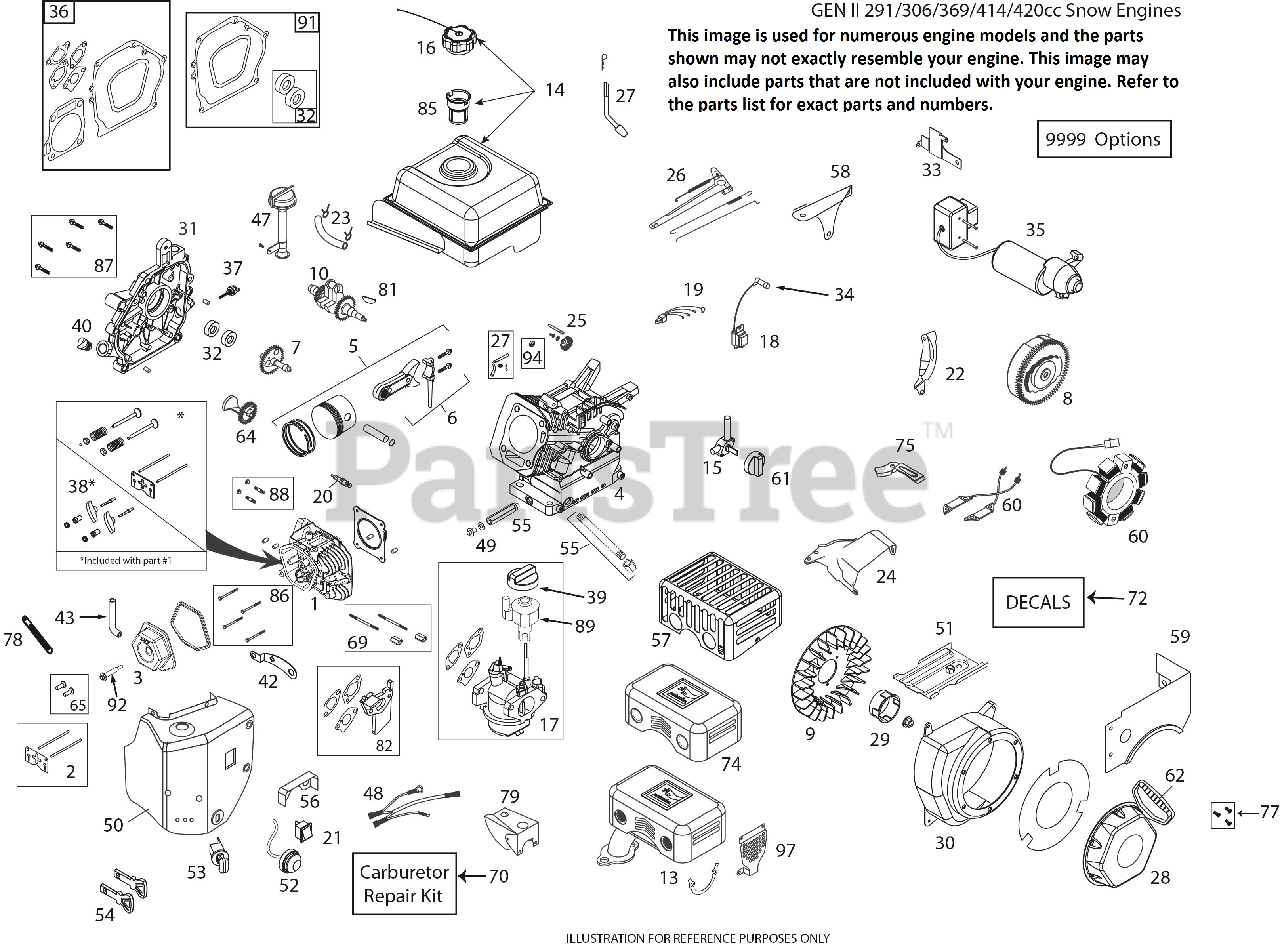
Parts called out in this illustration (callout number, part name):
1	CYLINDER HEAD ASSY (W/GASKET)
2	PUSH ROD & PLATE KIT (W/GSKT)
3	VALVE COVER (W/GASKET)
5	PISTON & ROD ASSEMBLY
6	CONNECTING ROD ASSEMBLY
7	CAMSHAFT - MCR
8	FLYWHEEL - ELECTRIC START
9	COOLING FAN - FLYWHEEL
10	CRANKSHAFT (#17 KEYED)
13	MUFFLER ASSEMBLY
14	FUEL TANK (3.6L)
15	FUEL TANK ON/OFF VALVE
16	FUEL TANK CAP - (VENTED)
17	CARBURETOR (W/IDLE-DOWN)
18	IGNITION COIL (CDI) (STANDARD)
20	SPARK PLUG
21	ON/OFF SWITCH - ROCKER
23	FUEL HOSE KIT
24	SPEED CONTROL BRACKET (FIXED)
25	GOVERNOR GEAR ASSEMBLY
26	GOVERNOR ARM & LINK KIT
27	GOVERNOR ARM PADDLE
28	RECOIL STARTER, ROUND STYLE
29	STARTER CUP, ROUND STYLE
30	BLOWER HOUSING
31	CRANKCASE COVER ASSY
32	OIL SEAL KIT
33	ELECTRIC START SWITCHBOX BRKET
34	SPARK PLUG BOOT (W/MTL SHIELD)
35	230V EU ELECTRIC STARTER
36	ENGINE GASKET KIT
37	SMALL BLACK OIL DIPSTICK
38	ROCKER ARM KIT (W/GASKET)
39	CHOKE CONTROL KNOB (RED)
40	NON-REMOVABLE PLASTIC PLUG
43	BREATHER TUBE (291/369/414CC)
47	HIGH OIL-FILL TUBE & CAP
48	WIRE HARNESS
49	OIL DRAIN PLUG (W/WASHER)
50	HEATER BOX KIT
51	SHIELD - CYLINDER
52	PRIMER BULB WITH HOSE
53	SAFETY KEY SWITCH (W/KEYS)
54	KEY, PUSH/PULL LCT (2/PACKAGE)
55	OIL DRAIN TUBE
56	CARBURETOR VAPOR SHIELD
57	CE MUFFLER HEAT SHLD CPC#22031
58	SHIELD - GOVERNOR LINKAGE
59	FUEL TANK SKIRT
60	CHARGING COIL (60-WATT AC)
61	FUEL CONTROL KNOB (RED)
62	STARTER GRIP-SNOW (DELUXE)
65	TAPPET KIT (SET OF 2)
69	CARB MTG STUD KIT 291CC SNOW
70	CARBURETOR REPAIR KIT
72	ARIENS 291 (ALL) SNW DCL KIT
75	WIRE GUARD PLATE
77	RECOIL BOLT KIT
81	WOODRUFFF FLYWHEEL KEY 5-PACK
82	CARBURETOR SPACER
85	FUEL TANK STRAINER
86	HEAD BOLT KIT 291-414CC
87	CRANKCASE COVER BOLT KIT 291CC
88	MUFFLER MTG STUD KIT
89	SPEED CONTROL KNOB
91	CRANKCASE GASKET KIT(291-306)
92	VALVE COVER BOLT (SINGLE BOLT)
97	MUFFLER MANIFOLD SHIELD
9999	HIGH ALT JET - 291CC L11 CARB
9999	HARDWARE KIT (4 M6X10 FLG BLT)
9999	STARTER SWITCH SCREWS
